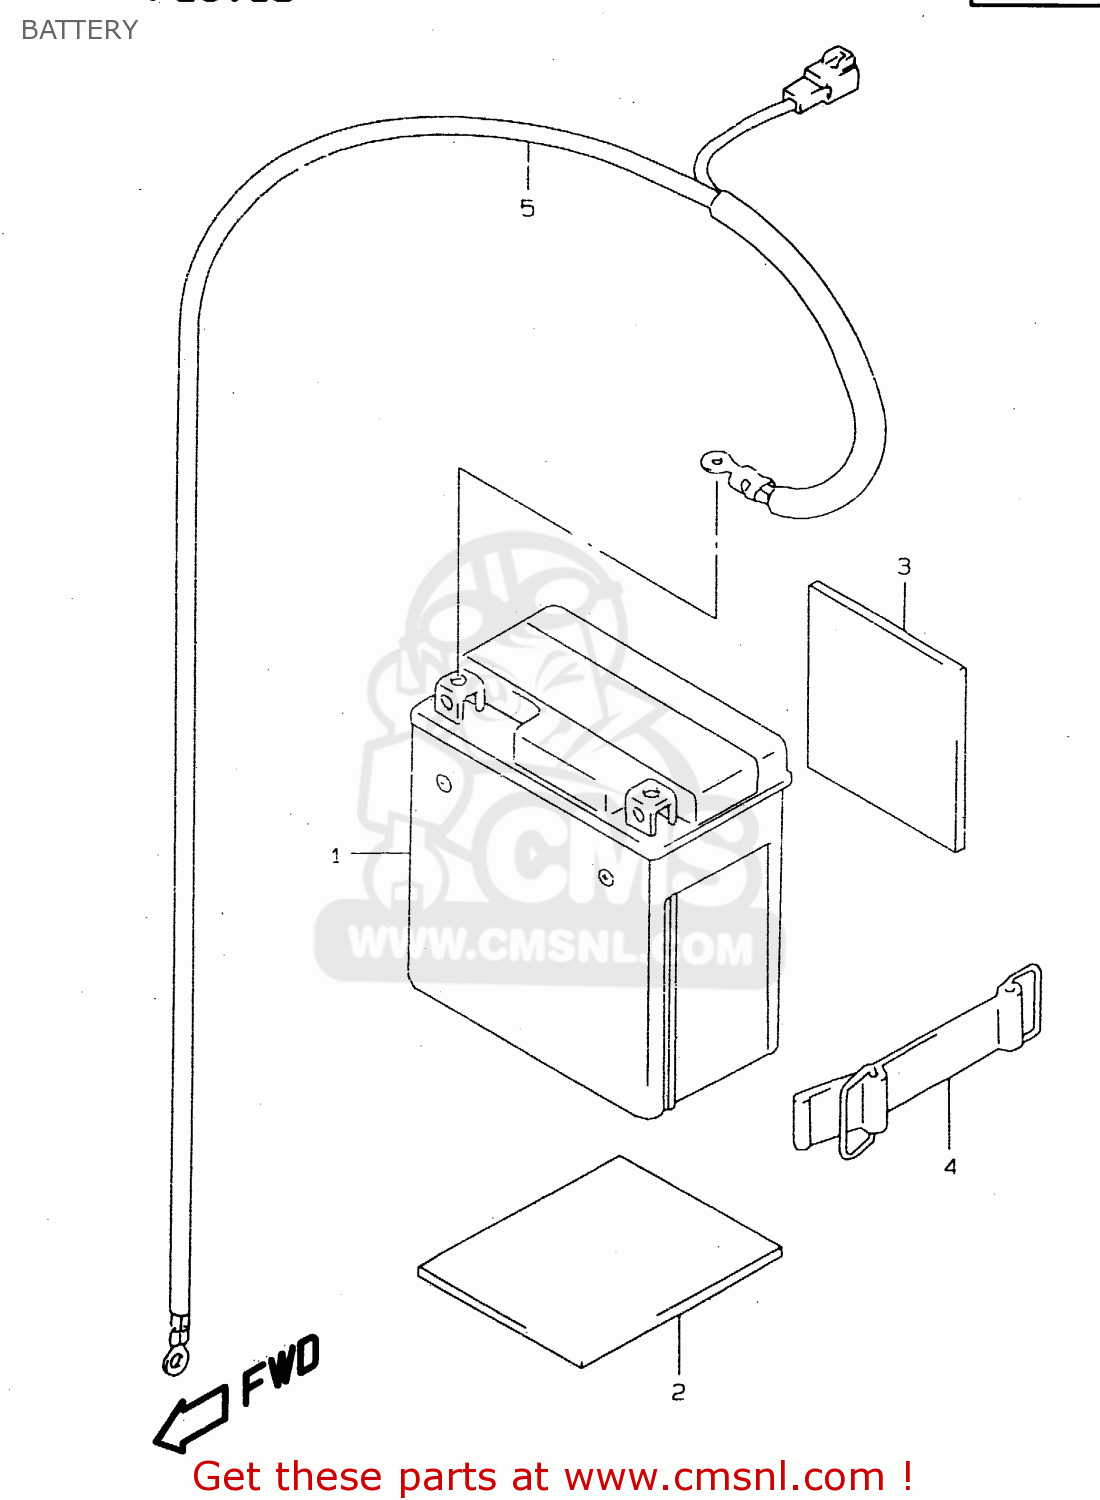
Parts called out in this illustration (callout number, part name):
1	BATTERY ASSY(YTX7L-BS,12V6AH)
2	PROTECTOR(170X95X3.0)
3	PROTECTOR(170X95X3.0)
4	BAND
5	WIRE,BATTERY MINUS
